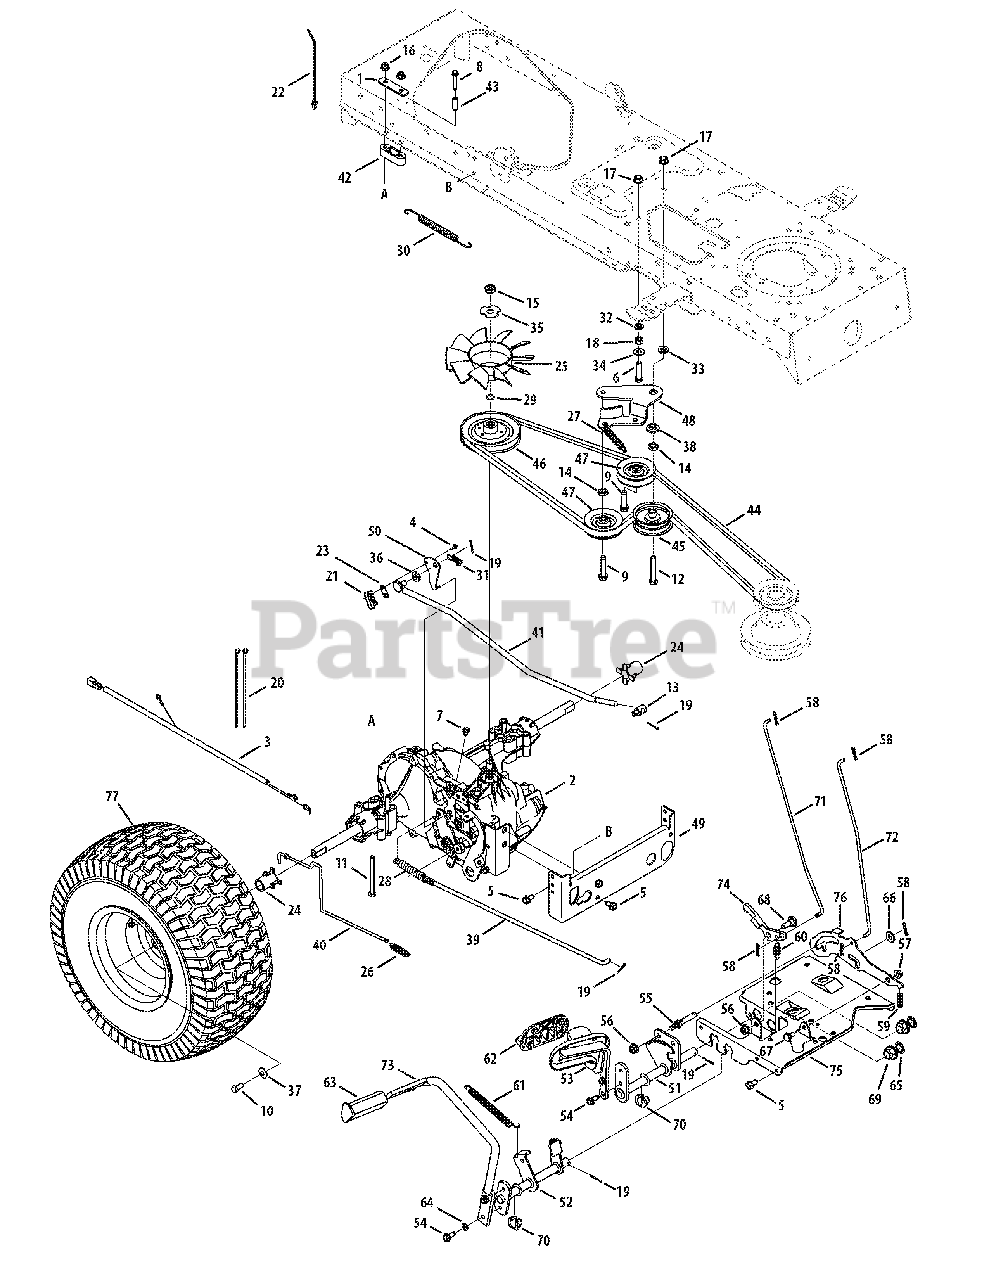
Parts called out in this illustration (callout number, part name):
1	Transaxle Mounting Bracket
2	Hydrostatic Transmission, 0510
3	Hydro Ground Harness Assembly
4	Screw, #8-18 x 0.500
5	Self-Tap Screw, 5/16-18 x .750
6	Hex Head Screw, 3/8-16 x 1.50 Gr5
7	Self-Tap Screw, 1/4-20 x 0.375
8	Self-Tap Screw, 1/4-20 x 1.500
9	Sems Self-Tap Screw, 3/8-16 x 1.500
10	Hex Head Screw, 5/16-24, .750 x Gr5
11	Hex Head Screw, 5/16-18 x 3.50 Gr5
12	Hex Head Screw, 3/8-16 x 2.25
13	Ferrule, 3/8-24 x .375
14	Jam Nut, 7/16-20
15	Flange Jam Nut, 1/2-20 Gr5
16	Flange Lock Nut, 5/16-18 Grf
17	Flange Lock Nut, 3/8-16 Grf
18	Hex Nut, 3/8-16 Gr5
19	Cotter Pin, 3/32 1.0
20	Cable Tie, 3/16 X .05 X 7.4
21	Short Spring Switch
22	Push Mount Cable Tie, 7.5 Lg
23	Insulator Plate Nut
24	Sleeve, .765 Id X 1.500 Lg
25	LT Hydro Fan
26	Extension Spring, .48 Od X 2.03
27	Extension Spring, .770 X 3.720 Lg
28	Extension Spring, .59 Od X 4.00 Lg
29	Wire Ring
30	Extension Spring, .500 Dia X 7.0 Lg
31	Extension Spring, 3/8 Od X 1.44 Lg
32	Lock Washer, 3/8 Regular Duty
33	Flat Washer, .385 X 1.0 X .135
34	Flat Washer, .406 X .875 X .059
35	Lock Washer, Hydro Trans.
36	Flat Washer, .407 x .812 x .135
37	Belleville Washer, .340 X .872 X .060
38	Shoulder Spacer, 1.00 X .38 X .38
39	Hydro Brake Rod
40	Hydro Bypass Rod
41	Hydro Control Rod
42	Spacer, T-Axle .68
43	Spacer, .260 X .372 X 1.030 Lg
44	V-Belt, 4l X 78 Lg Poly
45	Flat Idler Pulley, 2.75 Od
46	Input Pulley, 4.13 Dia
47	Idler Pulley, V-Type X 3.06
48	Center Double Idler Bracket
49	Hydro Torque Trans. Bracket
50	Light Switch Actuator Bracket
51	Hydro Control Assembly
52	Brake Control Assembly
53	Hydro Control Pedal Assembly
54	Self-tap Screw, 5/16-18 x 0.750
55	Pin, 3/8-16 X 2.68lg
56	Flange Lock Nut, 3/8-16 Grf
57	Flange Lock Nut, 5/16-18 Gr5
58	Cotter Pin, .072 Dia. X 1.13 Lg
59	Compression Spring, .405 X 1.17
60	Extension Spring, .50 Od X 1.41 Lg
61	Extension Spring, .50 Dia X 6.37 Lg
62	Drive Pedal Pad
63	Brake Control Pad
64	Lock Washer, 5/16, Regular Duty
65	Flat Washer, .64 X 1.24 X .06
66	Flat Washer, .385 X .870 X .092
67	Shoulder Bolt, .435 X .160, 5/16-18
68	Shoulder Bolt, .500 X .270, 3/8-16
69	Hex Flange Bearing
70	Hex Flange Bearing
71	Brake Lock-Rod
72	Cruise Control Rod
74	Latch, cruise
75	Steering Support Bracket
76	Hydro Lockout Bracket
77	Tire Assembly Complete 20 x 8 x 8
77	Tire Assembly Complete 20 x 10 x 8
